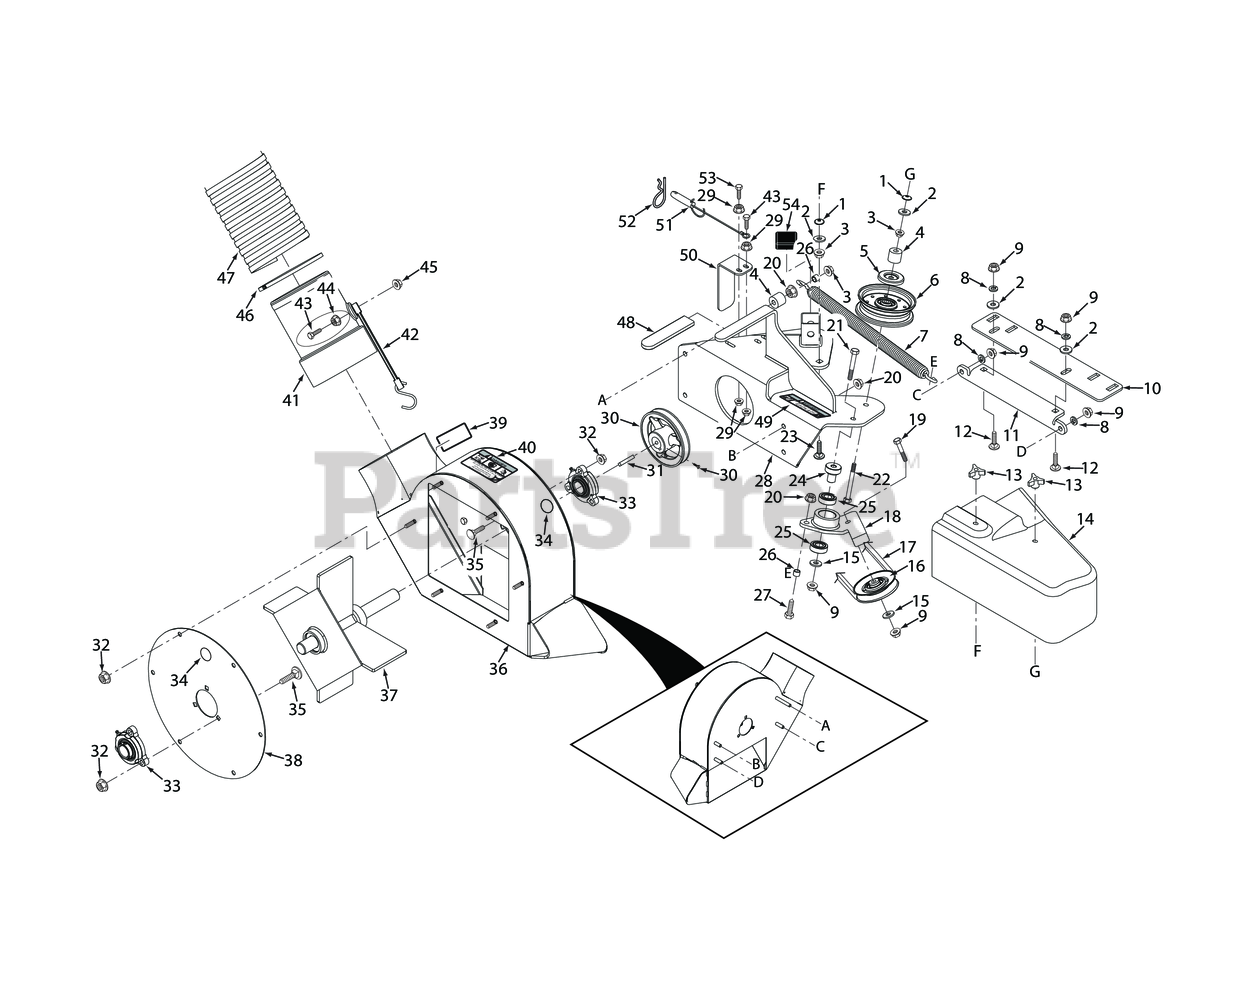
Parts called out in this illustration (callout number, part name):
1	Nut, Push-On - 3/8" Dia.
2	Flatwasher, 3/8" Special (.391 x .938 x .105)
3	Bolt, Hex Head 3/8-16 x 1" Ser. Flg.
4	SPACER, J-PULL ROD
5	Quick Pin, 5/16" Dia.
6	Pulley, Idler 4" Dia. - 61" & 72"
7	Spring, Helper (61" Cutter Deck Only)
8	Lockwasher, 3/8" Spring, Kawasaki FX / FS
9	HEX NUT, ELASTIC STOP LOCK, 3/8-16
10	Plate, Blower Catch
11	Plate, Catch Mounting
12	SHORT SQ. NECK CARRIAGE BOLT, 3/8-16 X 1-1/4"
13	Wing Nut, 3/8-16 (Small) Top side
14	Belt Cover, 48GC-VRII
14	Belt Cover, 52GC-VRII
14	Belt Cover, 61GC-VRII
15	Flatwasher, 3/8 (.391 x .938 x .105 HD) Grade 8
16	Pulley, 3-1/2" O.D., GC-STT 52"
17	Belt, GC-STWC 61"
17	Belt, GC-STC-61V / STCII-61V
18	Idler Arm Assembly, 48/52GC-VRII (INCL. 9,15,16,17,19,20,25,26,27)
18	Idler Arm Assembly, 61GC-VRII (INCL. 9,15,16,17,19,20,25,26,27)
19	Capscrew, Hex Head 3/8-16 x 2.0"
20	NUT, 3/8-16 SERRATED FLANGE HEX HEAD
21	Bolt, Hex Head 3/8-16 x 2-1/4" - 61"
22	Bolt, Hex Head 3/8-16 x 3-1/2" Full Thread
23	Bolt, RDHD Carr. 3/8-16 x 1-1/2 (52" & 61")
24	Pivot, Idler - 61" & 72"
25	BEARINGS, BALL, NEUTRAL RETURN
26	Spacer, Deck Assist
27	Bolt, Hex Head 3/8-16 x 1-1/4" Grade 8
28	Blower Mounting Frame w/ Decal
29	NUT, 1/4-20 SERRATED FLANGE HEX HEAD
30	Pulley, 4-3/4" O.D. - 1" Bore
31	KEY 1/4 X 1/4 X 1 1/2"(FOR 1" CRANKSHAFT
32	Nut, Serrated Flange 5/16-18 (Right Front Engine Mounting, Briggs and Kohler Only)
33	Bearing Assembly
34	Decal, Grease Point
35	Bolt, Carriage 5/16-18x1" (large frame units only)
36	Blower Housing Weldment w/Decals
37	FAN WLMT W/ BRGS, 6"
38	COVER, BLOWER HOUSING
39	Decal, Rotating Blower
40	Decal, Danger
41	Adapter, Blower GC-STC,
42	Rubber Strap 7-3/4"
43	SERR. FLG. HEX HEAD CAPSCREW, 5/16-18 X 3/4
44	Flatwasher, 1/4" (.312 x .750 x .065")
45	HEX, NUT, ELASTIC STOP LOCK, 1/4-20
46	Clamp, 6-1/2"
47	Hose, 6" x 36" Long
48	Grip, Deck Latch Lever
49	Decal, Warning - Belt Cover
50	Belt Cover
51	Pin, Ring 1/2" x 2-1/4"
52	Hair Pin Cotter, .177" x 3-1/4"
53	Bolt, Hex Head, 1/4-20 x 1-1/2"
54	Cap, Square Vinyl
